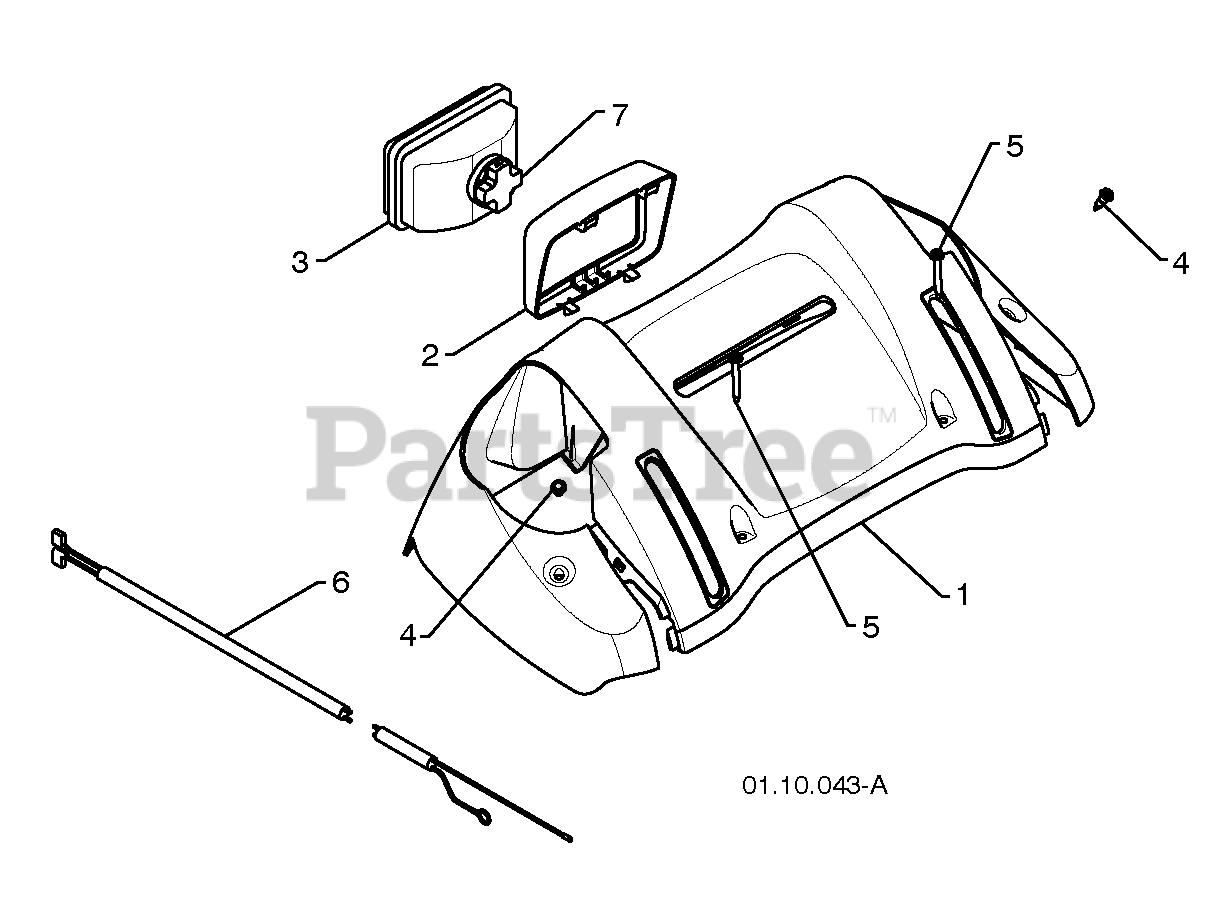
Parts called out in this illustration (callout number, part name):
1	CONSOLE PANEL GRAY
2	HEADLIGHT BEZEL GRAY
3	FLOOD HEADLIGHT
4	SHOULDER SCREW 10-24 X .625
5	SCREW 10-24 X 1.25
6	WIRE HARNESS
